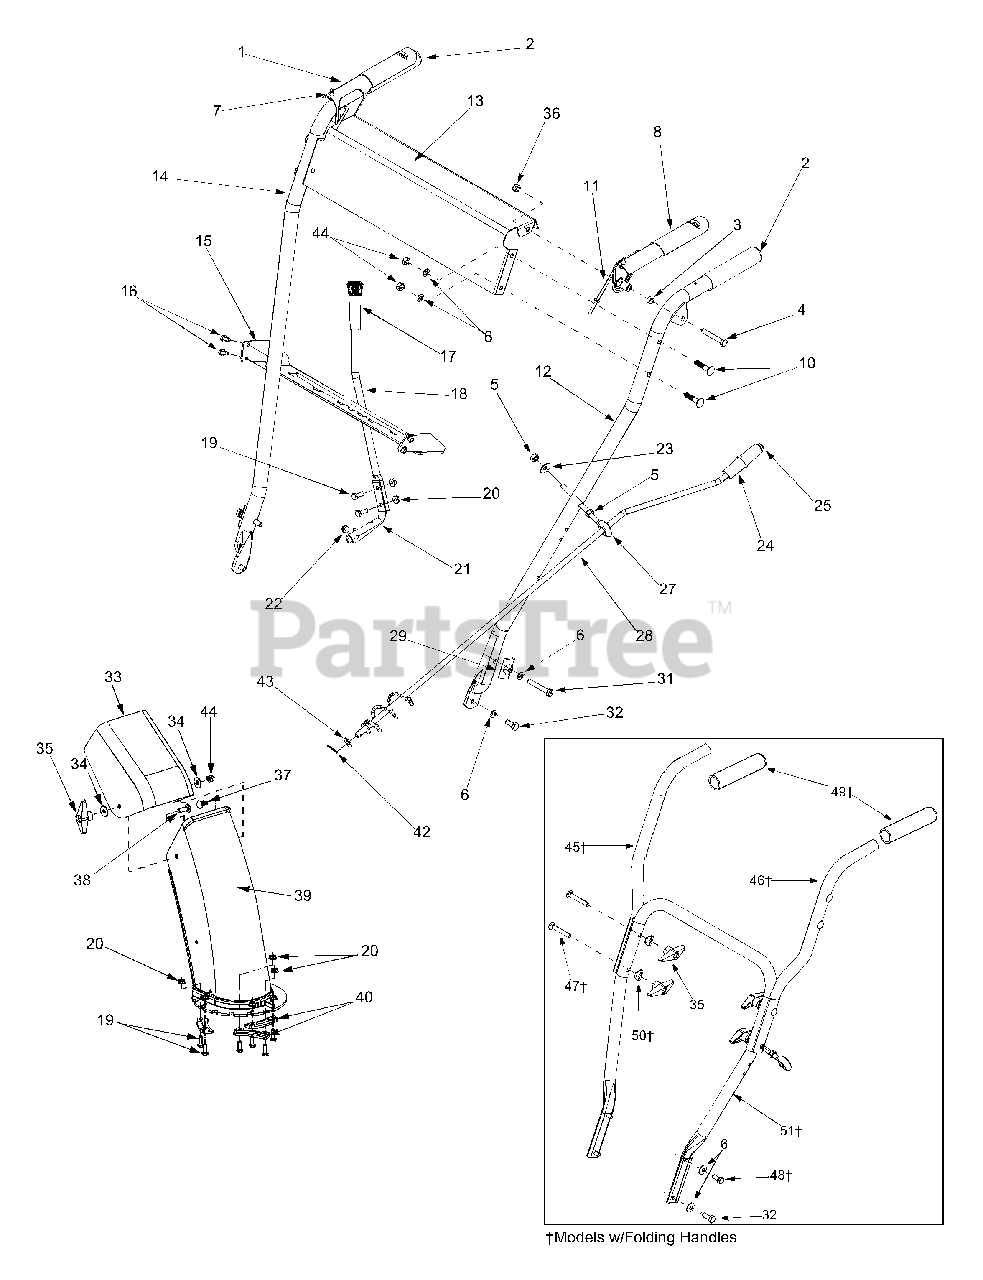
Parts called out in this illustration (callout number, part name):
1	Clutch Lever Assembly RH - Black
3	Spacer.325 ID x.460 OD
4	Hex Cap Screw 5/16 -18 x 2.0
5	Hex Nut 5/16-18
6	Lock Washer 5/16
7	Rubber Bumper
8	Clutch Lever Assembly LH - Black
10	Carriage Bolt 5/16-18 x 1.50
11	Z - Cable Fitting
16	Hex Washer Screw 1/4-20 x.50
19	Hex Cap Screw 1/4-20 x.75
20	Hex Lock Nut 1/4-20
21	Shift Lever Spring
22	Hex Washer Screw 1/4-20 x 1.0
23	Bell Washer
24	Chute Knob - Black
25	Push Cap
27	Eyebolt
28	Chute Directional Control Assembly
29	Handle Tab
31	Hex Cap Screw 5/16-18 x 2.00
32	Hex Cap Screw 5/16-18 x.75
33	Upper Chute
34	Washer 5/16
35	Knob - Black
36	Hex Lock Nut 5/16-18
37	Carriage Bolt 5/16-18 x.75
38	Carriage Screw 5/16-18 x 1.0
39	Lower Chute
40	Flange Keeper
42	Cotter Pin
43	Flat Washer 3/8
44	Hex Patch Nut 5/16-18 Gr. 5
48	Hex Cap Screw 5/16-18 x 1.00
49	Grip
50	Saddle Washer
